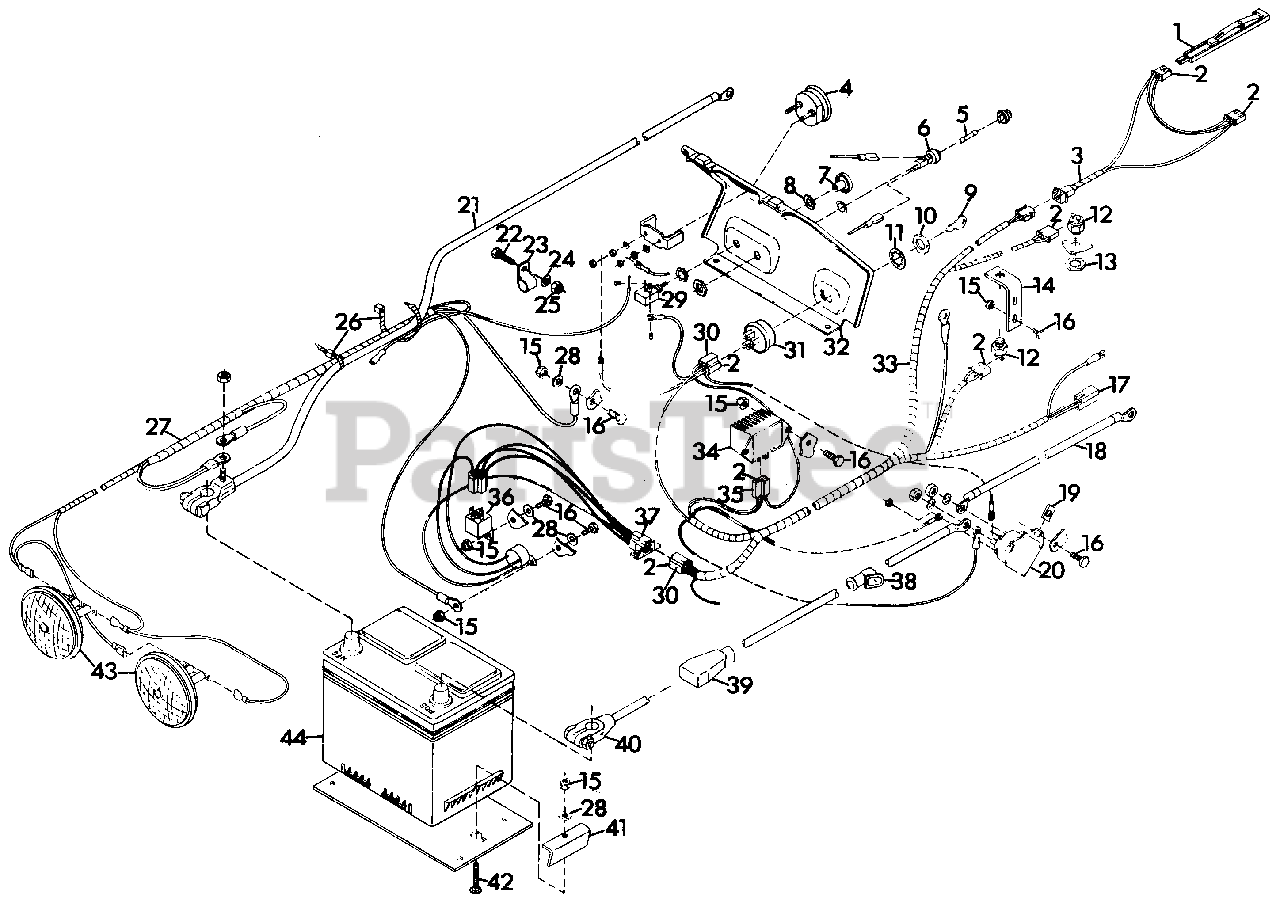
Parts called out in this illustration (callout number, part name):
1	SWITCH, SEAT
2	TERMINAL
3	HARNESS, WIRING SEAT SWITCH
4	GAUGE, AMMETER
5	FUSE, 30 AMP AGC 30
6	FUSE, PANEL
7	KNOB, LIGHT SWITCH
8	NUT, SPECIAL LIGHT SWITCH
9	KEY, IGNITION SWITCH
10	NUT, JAM 9/16-24
11	WASHER, LOCK 9/16 INT. TOOTH
12	SWITCH, INTERLOCK
13	NUT, STAMPED 9/16-18
14	BRACKET, SWITCH
15	NUT, LOCK 1/4-20
16	BOLT, HEX 1/4-20X.75
17	CONNECTOR
18	CABLE, STARTER
19	NUT, SPEED 1/4-20
20	SWITCH, MAGNETIC
21	CABLE, NEGATIVE BATTERY
22	BOLT, HEX 5/16-18X1.00
23	CLAMP, NYLON
24	WASHER, FLAT .344X.688X.065
25	NUT, LOCK 5/16-18
26	TIE, CABLE
27	HARNESS, WIRING GROUND AND LIGHT
28	WASHER, FLAT .281X.625X.065
29	SWITCH, LIGHT
30	CONNECTOR
31	SWITCH, IGNITION
32	PANEL, INSTRUMENT
33	HARNESS, WIRING
34	REGULATOR, RECTIFIER
35	CONNECTOR
36	RELAY
37	MODULE, TIME DELAY
38	BOOT, BATTERY CABLE
39	COVER, BATTERY TERMINAL
40	CABLE, BATTERY TO MAGNETIC SWITCH
41	CLAMP
42	BOLT, 1/4-20X1.75 RD HD SQ NK
43	HEADLIGHT
44	BATTERY, 12 VOLT
NS	WASHER, LOCK 1/4 EXT. TOOTH TYPE A
